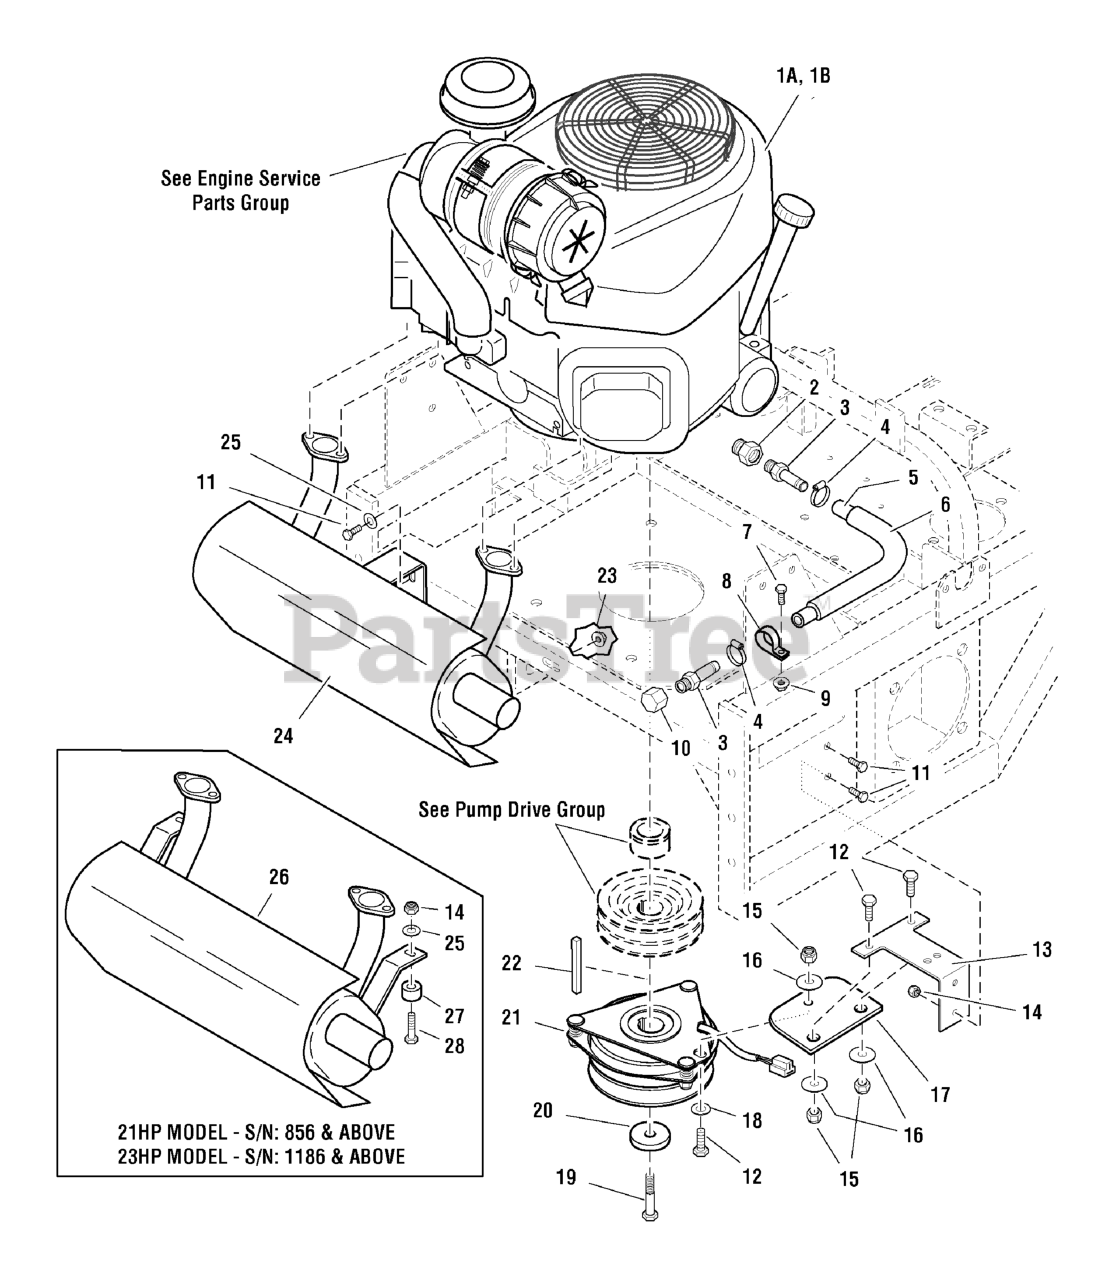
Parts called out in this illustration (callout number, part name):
1B	FUEL FILTER
1B	OIL FILTER (49065-2078)
2	ADAPTER, Oil Drain
3	FITTING, 3/8NPT-1/2" Hose, Straight
4	CLAMP, #6 Hose
5	HOSE, 9"
6	WIRE LOOM, 7"
7	BOLT, 1/4-20 x 3/4
8	CLAMP, Vinyl
9	NUT, 1/4-20 HEX SERR. FLANGE
10	CAP, 3/8 NPT
11	BOLT, 5/16-18 X 3/4 GD5
12	BOLT, 3/8-16 X 1" GD5 CZ
13	CLUTCH ANCHOR
14	NUT, 5/16-18 Hex Nylon Lock
15	NUT, 3/8-16 HEX NYLON LOCK
16	WASHER, 3/8" Fender
17	CLUTCH ANCHOR PAD
18	WASHER, 3/8 SAE
19	CRANKSHAFT BOLT, 7/16 x 2
20	SPACER, .45 x 1.88 x .38
21	ELECTRIC CLUTCH
22	KEY, 1/4 SQ. X 3-1/2
23	NUT, 5/16-18 HEX SERRATED FLANGE (SMALL)
25	WASHER, 5/16" SAE
26	MUFFLER, 21HP-25HP KAWASAKI ENGINES
27	SPACER, .39 x 1.00 x .75
28	BOLT, 5/16-18 x 1-1/2
